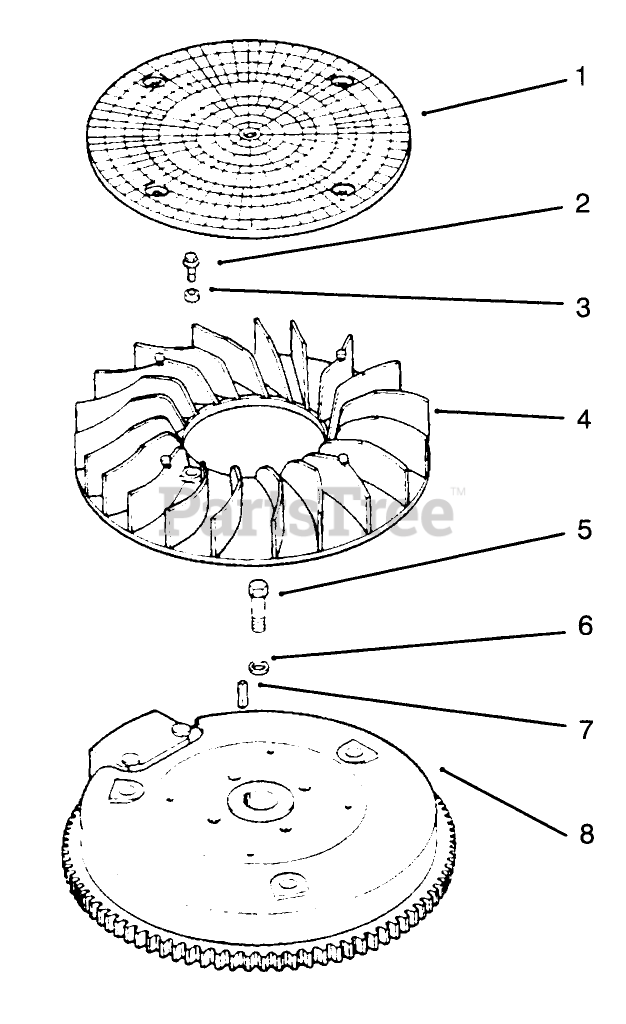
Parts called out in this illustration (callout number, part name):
1	Screen-Grass
2	Screw-Hex Wash. Hd.
5	Screw-H.C.
6	Washer-Flat
8	Flywheel
